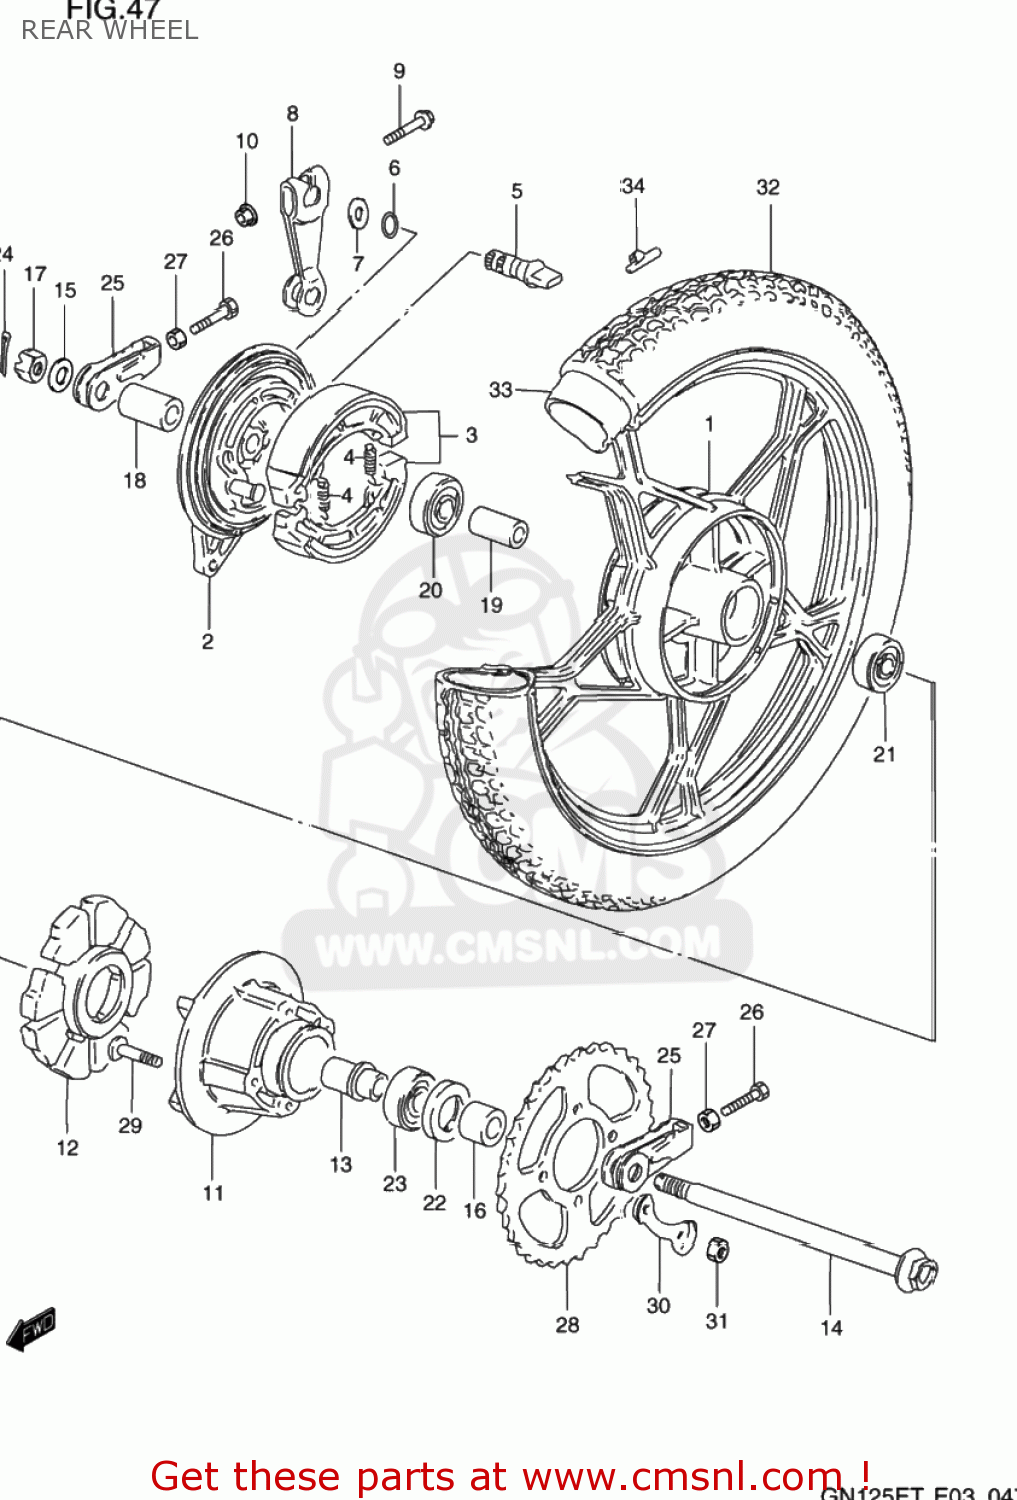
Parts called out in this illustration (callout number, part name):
1	WHEEL,RR(2.15X10)
2	PANEL,RR BRAKE ANCHOR
3	SHOE,BRAKE
4	SPRING(L:34)
5	CAM,BRAKE
6	O-RING (D:2.4 ID:13.8)
7	WASHER (14.5X22X1.6)
8	LEVER,RR BRAKE CAM
9	BOLT
10	NUT
11	DRUM,RR SPROCKET MOUNTING
12	ABSORBER,RR HUB SHOCK
13	RETAINER,RR SPROCKET DRUM
14	AXLE,RR
15	WASHER
16	SPACER(15X28X19)
17	NUT
18	SPACER(15.2X26X33)
19	SPACER(15.3X21.7X63)
20	BEARING
21	BEARING
22	SEAL,OIL(28X47X7)
23	BEARING(20X47X14)
24	COTTER PIN
25	ADJUSTER,CHAIN
26	BOLT
27	NUT
28	SPROCKET,REAR
29	BOLT
30	WASHER
31	NUT
32	TIRE,RR(3.50-16 4PR)
33	TUBE
34	BALANCER,WHEEL
